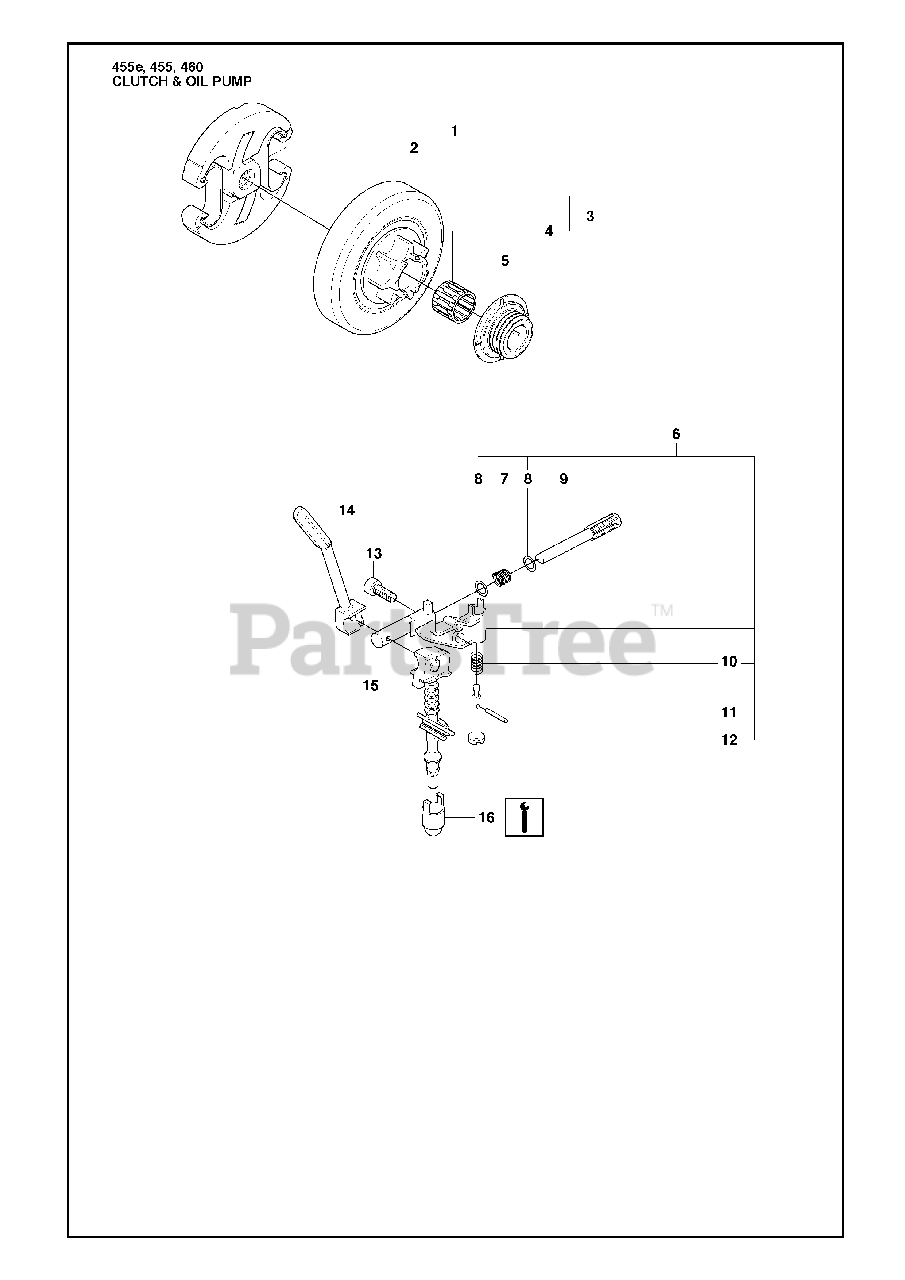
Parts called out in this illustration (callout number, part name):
3	CLUTCH DRUM
4	NEEDLE BEARING
5	GEAR WORM OILER
6	OIL PUMP ASSY
9	PUMP PISTON
15	RP OIL HOSE
16	OIL SCREEN
